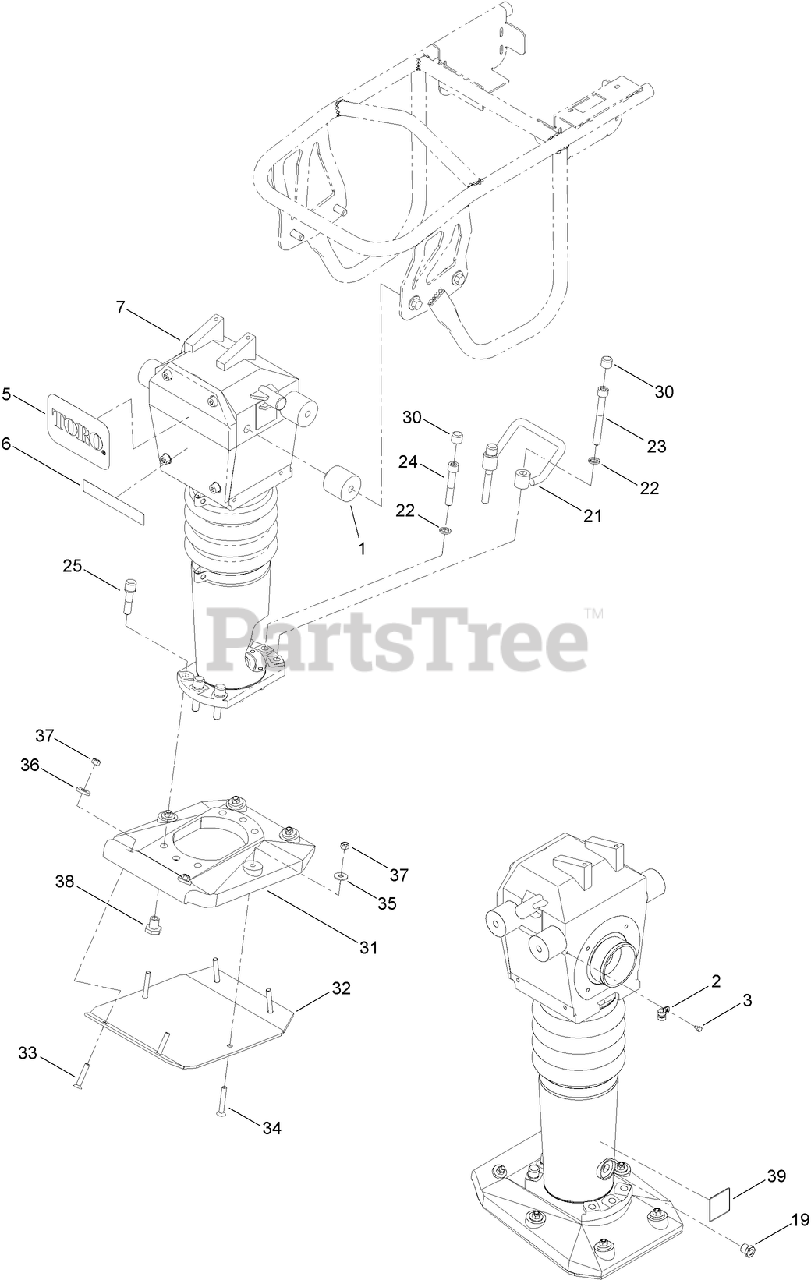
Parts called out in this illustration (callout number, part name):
1	MOUNT-SHOCK
2	CLAMP
3	SCREW-HH
5	DECAL
6	DECAL
7	RAMMER ASM
19	PLUG-SIGHT, OIL
21	GRIP-LIFTING
22	WASHER-LOCK
23	SCREW-HSH
24	SCREW-HSH
25	SCREW-HSH
30	CAP-PLASTIC
31	SHOE-PLASTIC, LIGHT
32	PLATE-SHOE
33	SCREW
34	SCREW-HSFH
35	WASHER-FLAT
36	WASHER-FLAT
37	NUT-LOCK, NI
38	INSERT-SHOE
39	DECAL-OIL LEVEL
